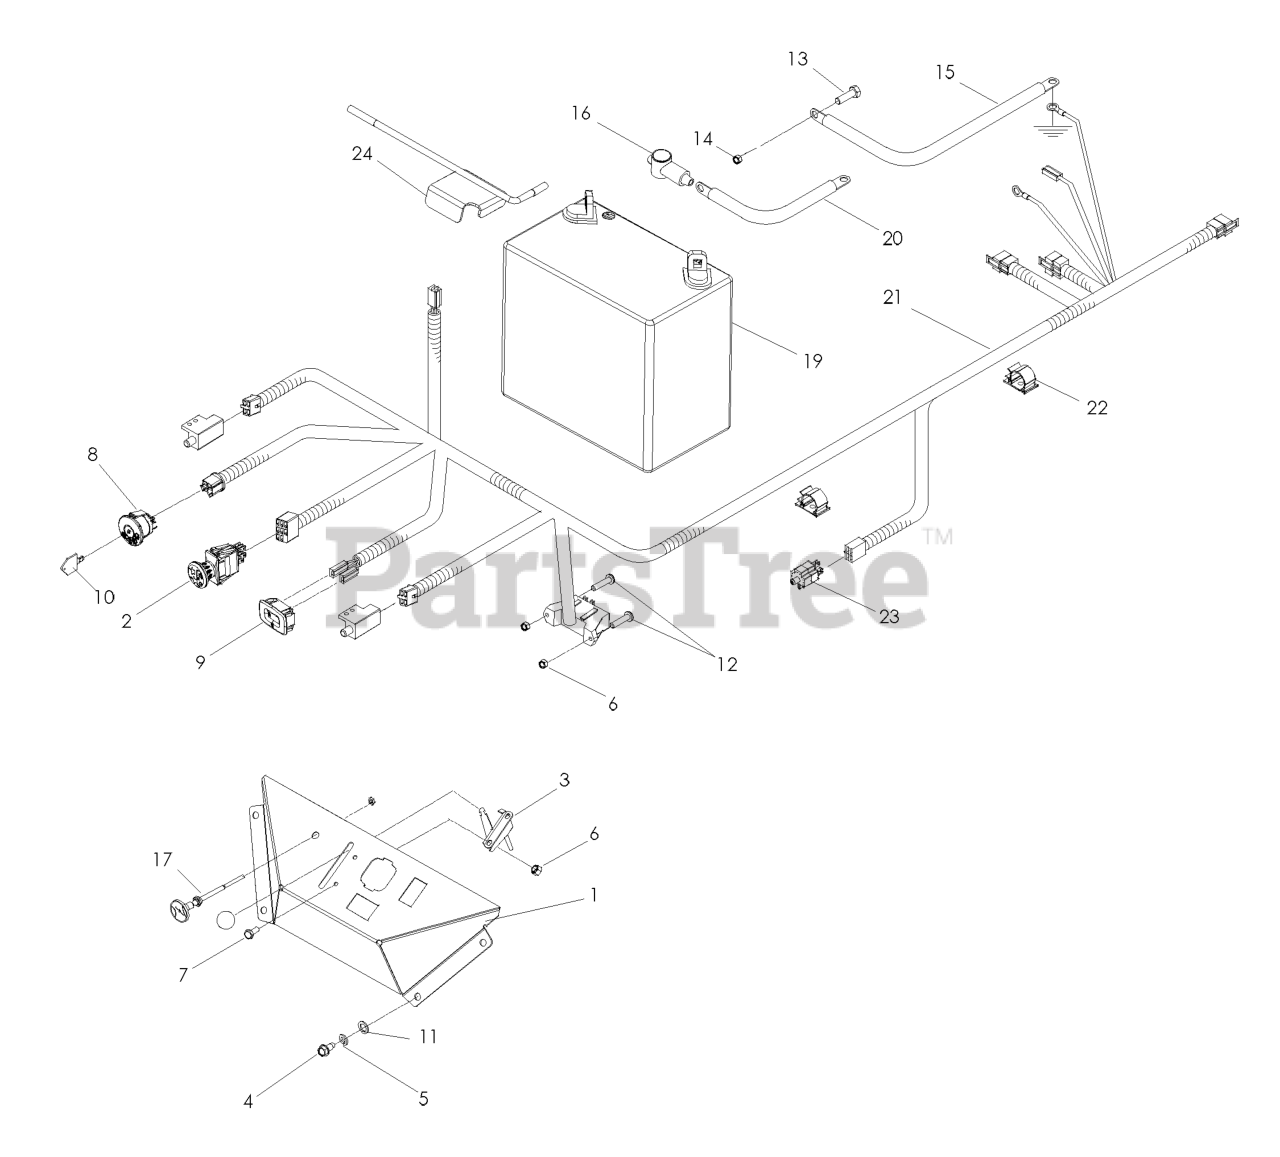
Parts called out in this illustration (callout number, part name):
1	CONSLE, ORANGE
2	SWITCH, PTO 10 AMP
3	THROTTLE CABLE
4	SCREW 1/4 X 5/8
5	LOCKWASHER 1/4"
6	NUT 10-24 NYLOC
7	HCS #10-24 X 1/2
8	RP IGNITION SWITCH
9	HOUR METER
10	KEY
11	WASHER 1/4 FLAT
12	SCREW, #1--24 X 1/2 SLOTTED
13	HCS 5/16C X 3/4
14	NUT 5/16 NYLOC
15	CABLE-NEGATIVE
17	CONTROL-CHOKE 57"
18	CABLE, CHOKE
18	CONTROL-CHOKE 51"
20	BATTERY, 12 V 330 AMP
21	CABLE POSITIVE, LONG
22	HARNESS, WIRING LZ/IZ
23	PUSH-MOUNT WIRE CLIP
24	SWITCH, BRAKE 3P
25	BATTERY HOLD DOWN
